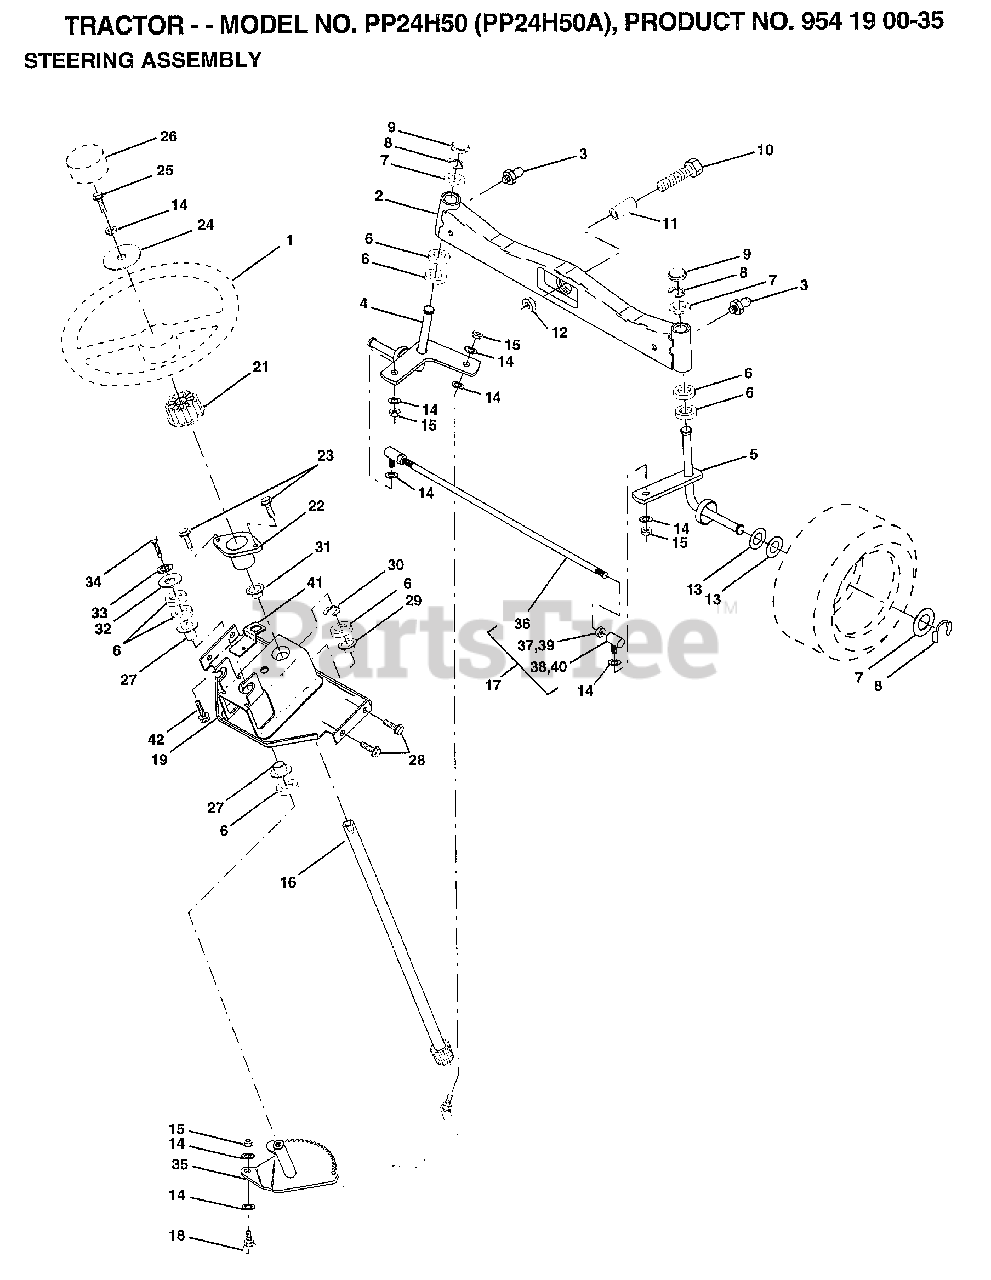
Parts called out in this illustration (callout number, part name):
3	ZERK M
4	SPINDLE ASM LH
5	SPINDLE ASM RH
6	WASHER .T
7	WASHER
8	RING
9	CAP
10	BOLT
11	SPACER BEARING
12	"NUT-LOC,FLANGE LT"
13	WASHER
14	LOCKWASHER
15	GRIPCO NUT
16	SHAFT.STEER.VGT
17	ROD.ASM.TIE.BALL
18	DRAGLINK.BALL.JOI
19	SUPPORT ASM-STEER
21	ADAPTER LT
22	"BUSHING,STEERING"
23	"SCREW-TT,10-32 FL"
24	WASHER T
25	BOLT
26	"INSERT,STR WHEEL"
27	COL. SRTG. BEAR.
28	SCREW
29	"FLANGE GT, BEAR."
30	KLIP RING
31	BUSHING.NYLINER.
32	WASHER
33	LOCKWASHER
34	BOLT
35	GEAR.ASM.SECTOR.
37	NUT
38	JOINT.RH
39	NUT
40	JOINT.LH
41	"BRKT-SW, INTER"
42	SCREW LT
